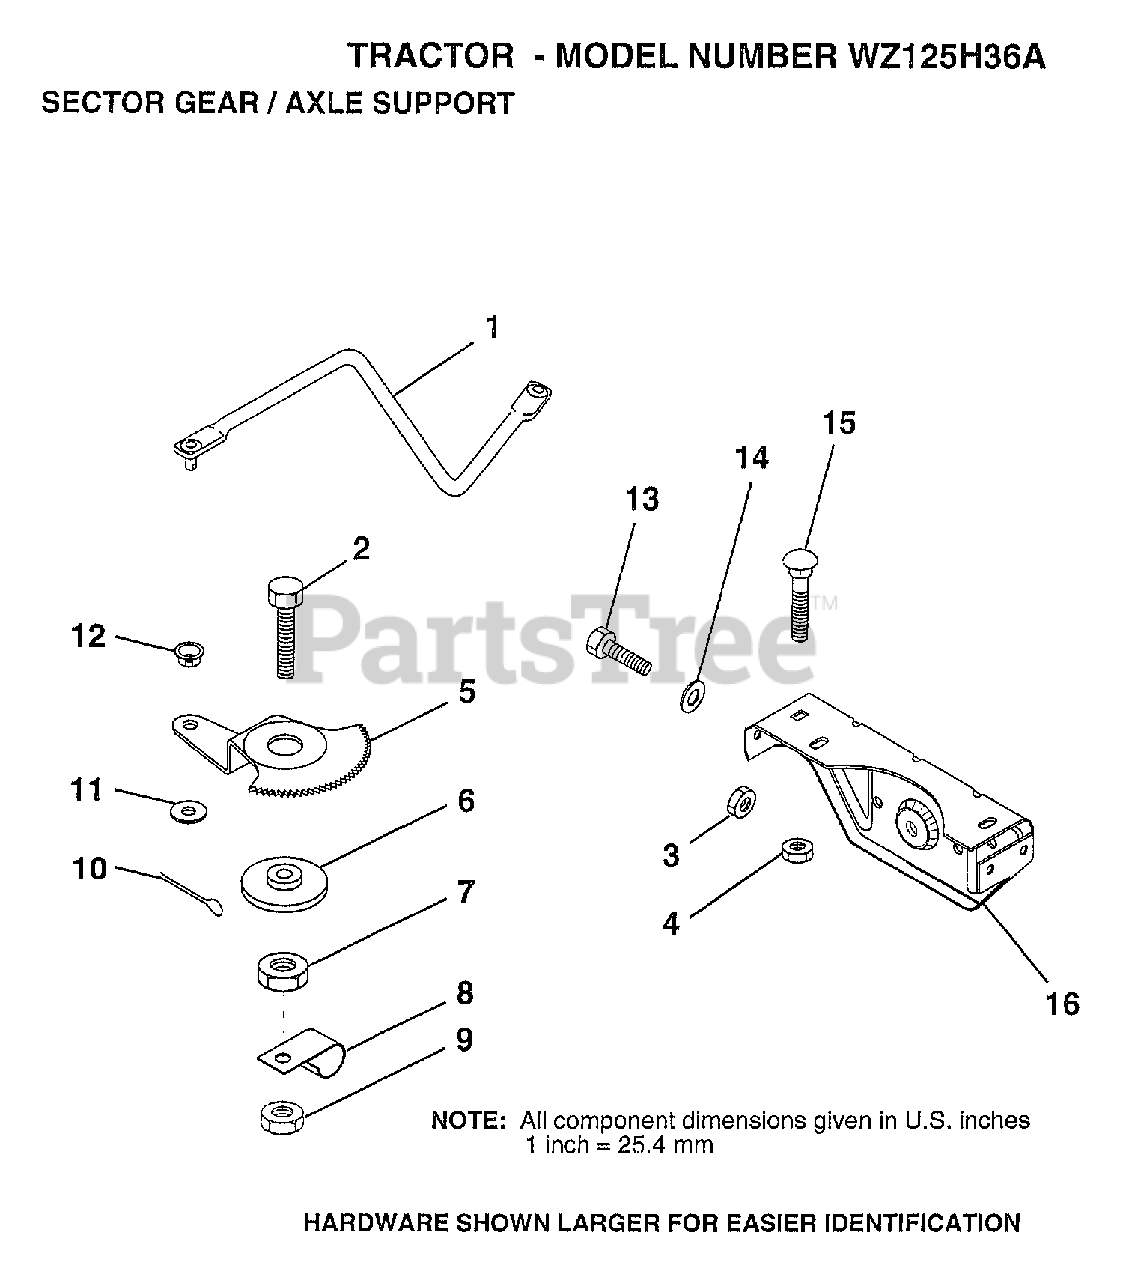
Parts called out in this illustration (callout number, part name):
1	DRAG LINK
2	"BOLT,HEX"
5	GEAR SECTOR
6	BUSHING
7	NUT
8	CLIP INSULATOR
9	NUT LTV
10	COTTER PIN
11	WASHER
12	BUSHING.DRAGLINK
13	BOLT
14	WASHER
15	BOLT
16	SUPT AXLE FRONT
